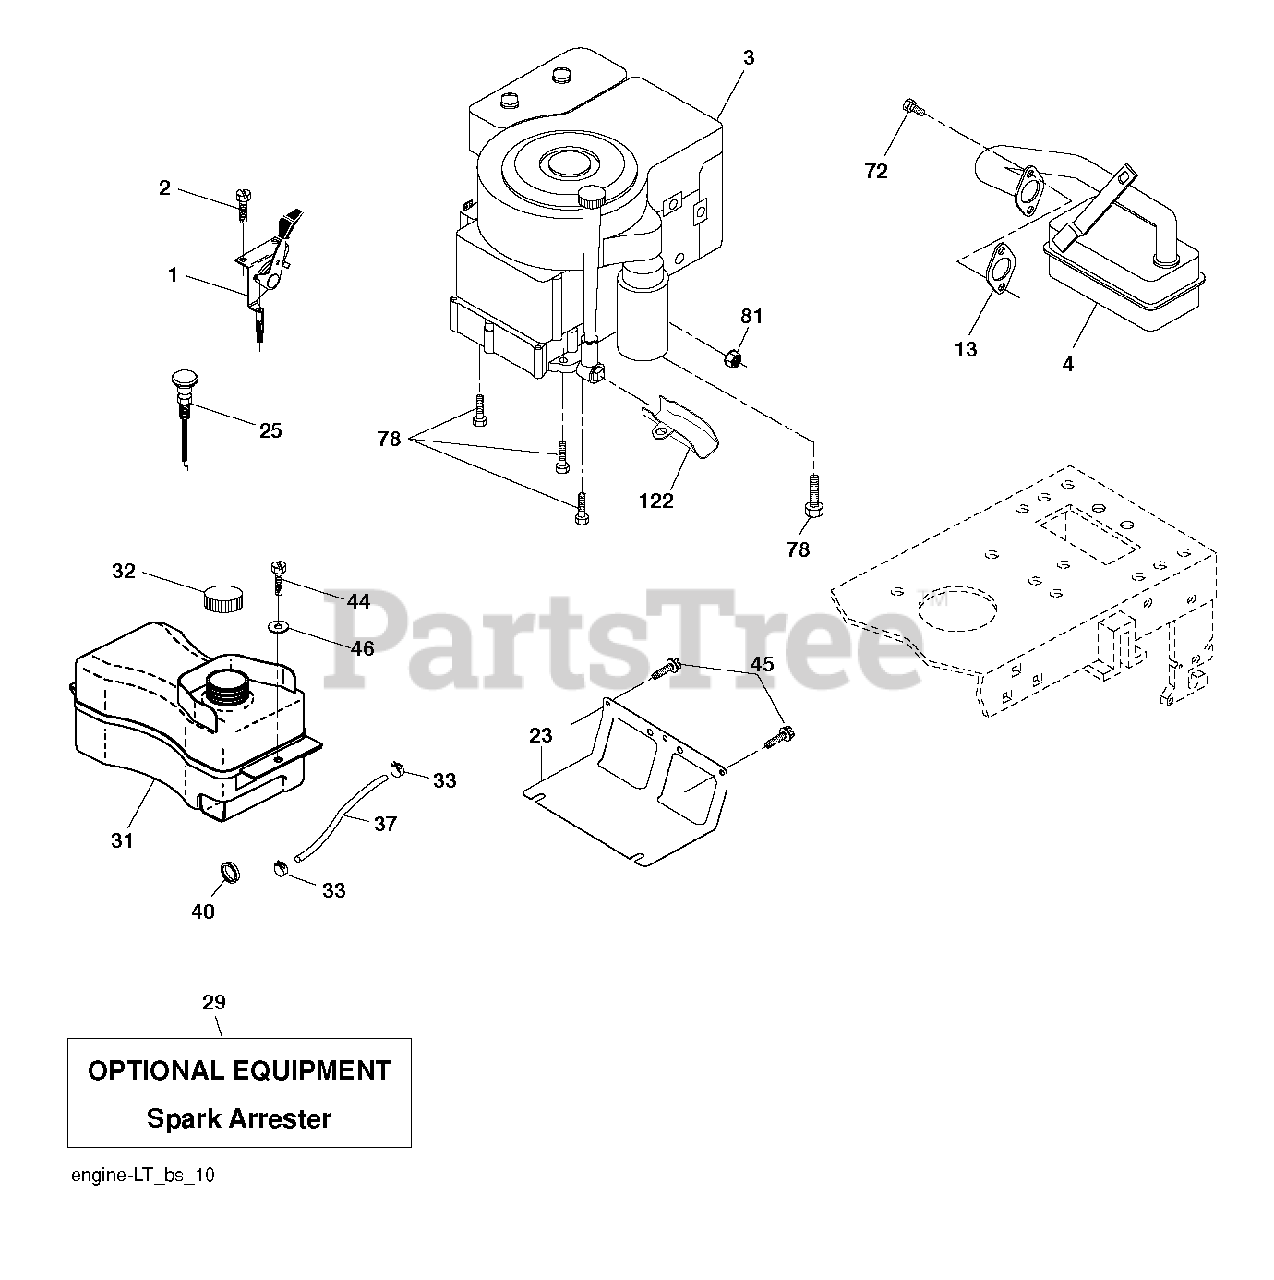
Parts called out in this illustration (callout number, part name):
1	CONTROL TH/CH FLAG
2	SCREW
13	REPL BY 532 27 22-93
23	SHEILD.BROWNING.DBR.GUARD
29	ARRESTER SPARK (OPTIONAL)
32	CAP ASM.FUEL.2.25"FR.
33	HOSE CLAMP
37	LINE.FUEL.20
40	GROMMET T
44	SCREW HEXWSHR 1/4-20X3/4
45	SCREW, 3/8-16X3/4
72	SCREW.SOCKET HD.5/16-1
78	SCREW.3/8-16
81	NUT
122	EXTENSION DRAIN OIL
